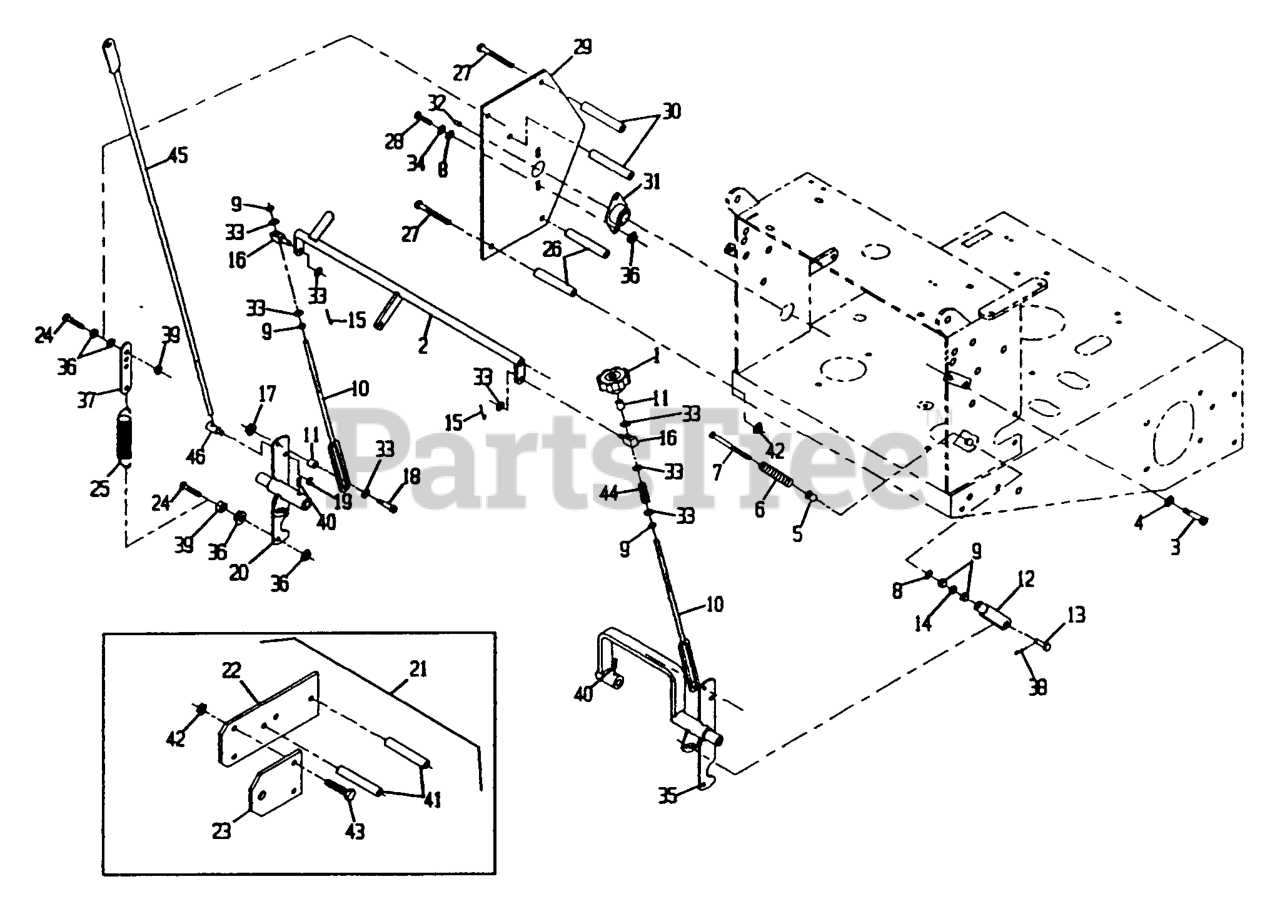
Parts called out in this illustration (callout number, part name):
1	KNOB-TRACKING
2	CRANK-CONTROL, SPEED
3	SCREW-HSH
5	BUSHING-FLANGED
6	SPRING-RETURN, NEUTRAL
7	BOLT-RETURN, NEUTRAL
12	YOKE-ADJUSTABLE
13	PIN-CLEVIS
18	SCREW-HSH
21	Sulky Hitch Kit, (Vik Hydro)
22	MOUNT-HITCH
23	Bracket, Hitch Adapter
25	SPRING-EXTENSION
26	SPACER-SHIELD
30	SPACER-SHIELD
31	BEARING-FLANGE, SIDE
34	WASHER-LOCK
37	TAB-SPRING, EXTENSION
38	PIN-COTTER
40	SCREW-SET
44	SPRING-COMPRESSION
45	ROD-LEVER, DRIVE
